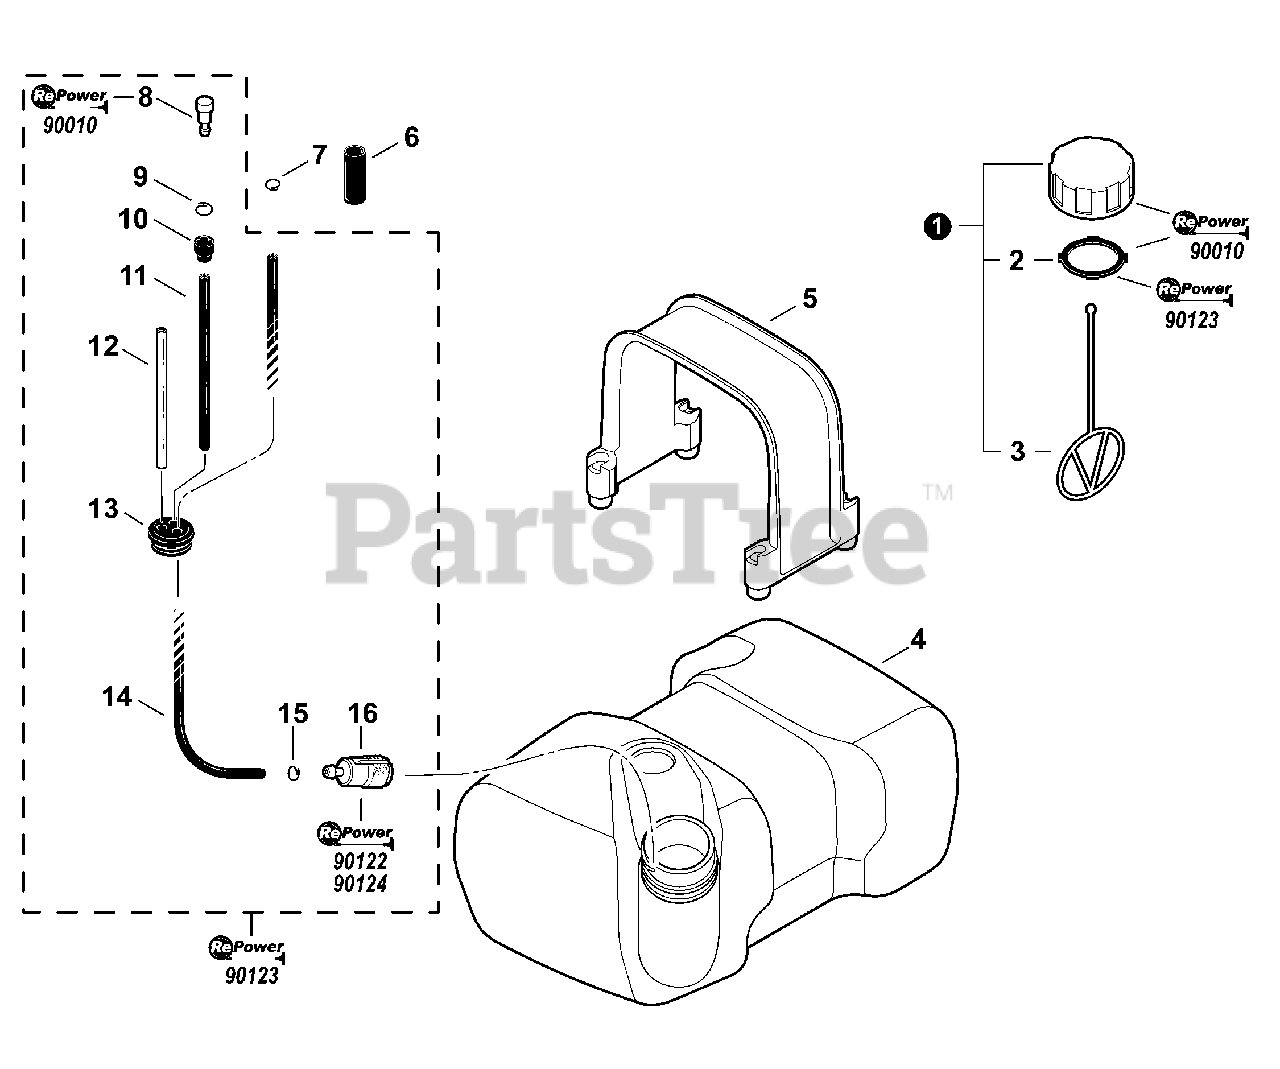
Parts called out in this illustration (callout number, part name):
1	CAP ASSY, FUEL
2	GASKET, FUEL CAP
3	CONNECTOR, CAP L= 100 MM
4	TANK, FUEL
5	RETAINER, FUEL TANK
6	TUBE, FUEL LINE 16×18×L40
7	CLIP 6 MM
8	VENT ASSY
9	CLIP Ø6.5 MM
10	HOLDER, VENT
11	PIPE, FUEL 3×6×130 BLACK
12	PIPE, FUEL RETURN 2.4×5×170
13	GROMMET, FUEL
14	PIPE, FUEL 3×5×240 BLACK
15	CLIP 6 MM
16	FILTER, FUEL 125-528
